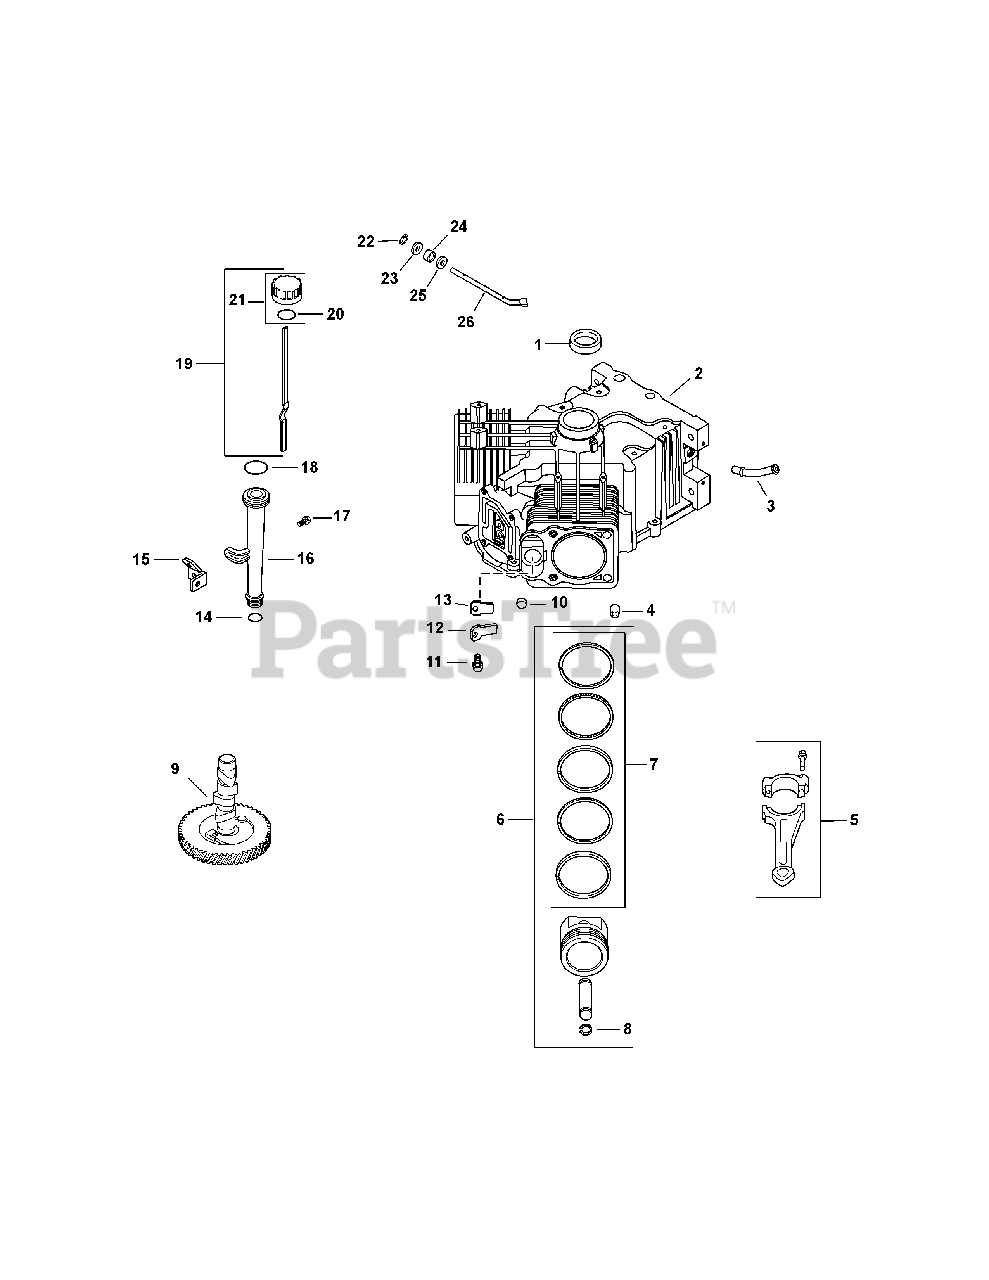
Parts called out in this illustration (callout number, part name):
1	SEAL, OIL (HELIX LIP)
2	CRANKCASE
4	PIN, LOCATING
5	ROD, ASSEMBLY CONNECTING (STD)
5	ROD, ASSY CONNECTING (.25 O.S.)
6	PISTON ASSY W/RING SET (STD) (includes 7, 8)
6	KIT,PISTON ASSY W/RING SET (.08)
6	KIT,PISTON ASSY W/RING SET (.25)
6	PISTON ASSY W/RING SET (.5)
7	RING SET, PISTON (STD)
7	RING SET, PISTON (.08)
7	RING SET, PISTON (.25)
7	RING SET, PISTON (.50)
8	RETAINER, PISTON PIN
9	KIT, CAMSHAFT
11	SCREW, FLG THD FRM M5X.8X10
12	RETAINER, BREATHER REED
13	REED, BREATHER
14	O-RING, LOWER OIL FILL TUBE
15	BRACKET, OIL FILL TUBE
16	TUBE ASSEMBLY
17	SCREW, FLG THD FRM M5X0.8X16
18	O-RING, UPPER OIL FILL TUBE
19	DIPSTICK, ASSY (includes 20, 21)
20	O-RING, DIPSTICK
21	KIT, OIL FILL CAP (YELLOW) (Includes 20)
22	RETAINER, RING
23	WASHER, FLAT 9 MM
24	SEAL, GOVERNOR CROSS SHAFT
25	WASHER, FLAT 11/32''
26	SHAFT, GOVERNOR CROSS
